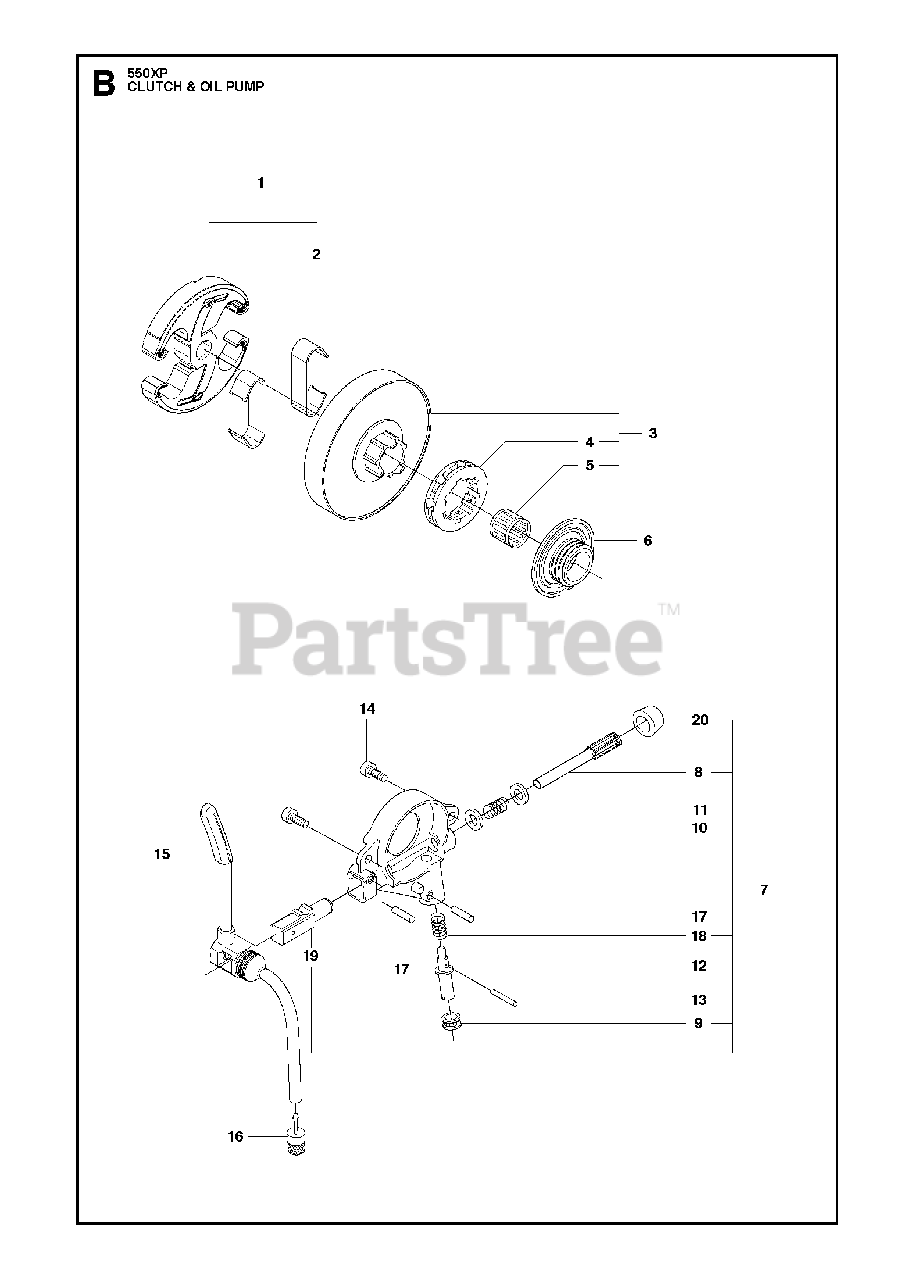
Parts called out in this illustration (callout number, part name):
1	CLUTCH ASSY
2	SPRING
3	CLUTCH DRUM ASSY
4	RIM SPROCKET 7T .325
5	SUPPORT BUSHING
6	WORM WHEEL
7	OIL PUMP ASSY
8	PUMP PISTON
9	CASING
10	WASHER
11	SPRING
12	RP ADJUSTING SCREW
13	PIN
14	SCREW IHSCM
16	OIL PLUMMET
17	PIN 3X10
18	SPRING
19	PUMP CYLINDER
20	PLUG
